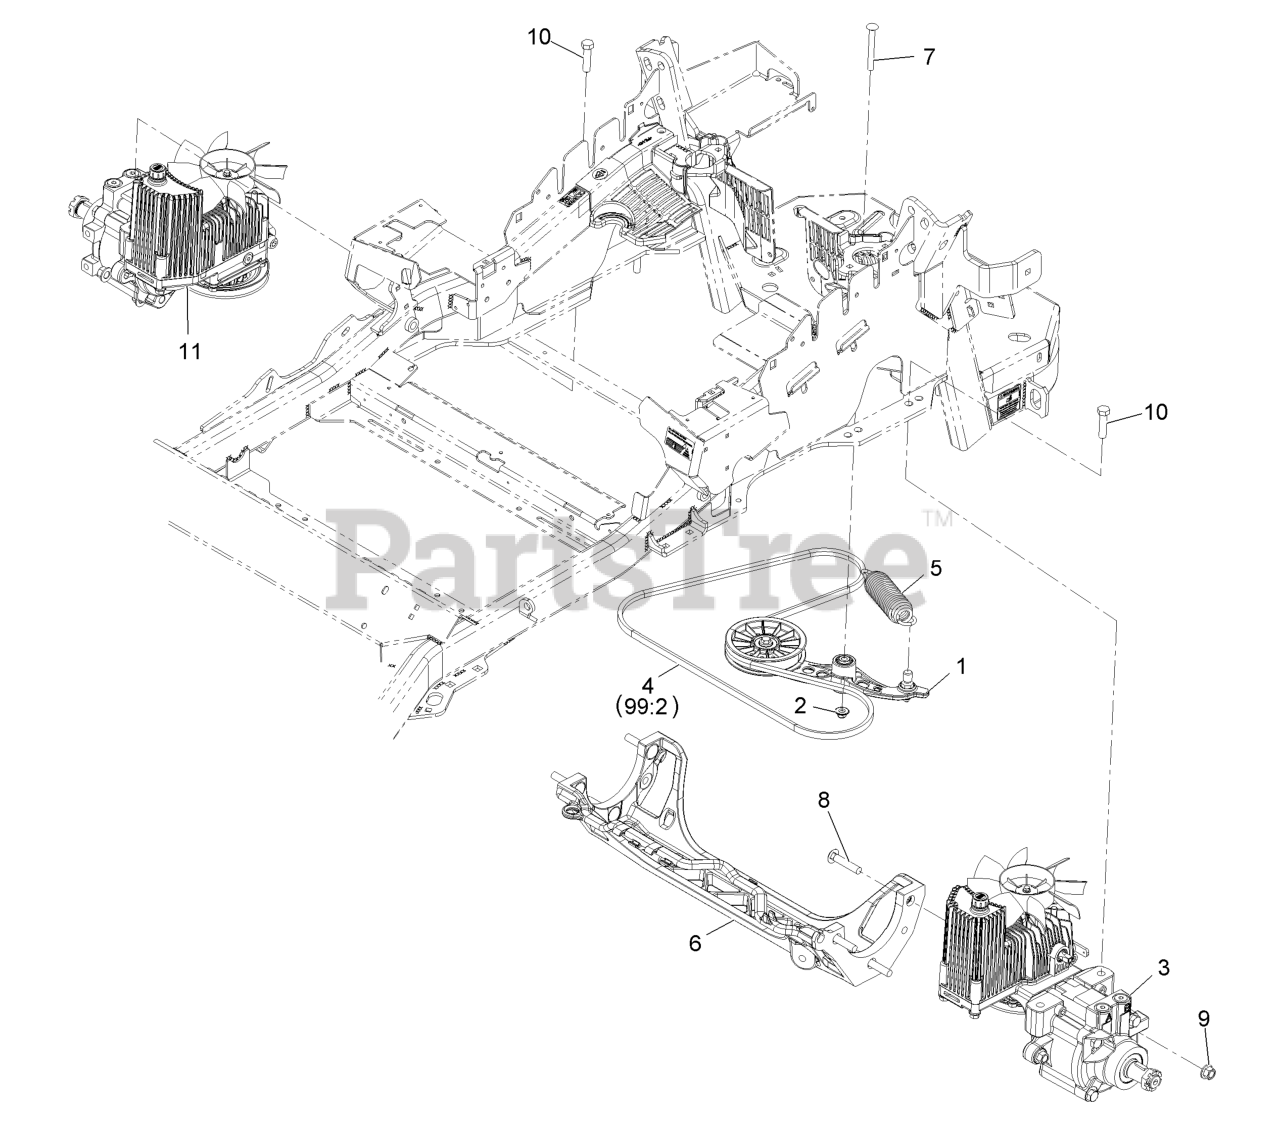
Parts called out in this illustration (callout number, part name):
1	PUMP IDLER ASM
2	Nut-Nyloc 3/8-16 Flg
4	BELT
5	SPRING-EXTENSION
7	BOLT-SHOULDER, CARRIAGE 3/8-16 X 3 1/2
8	SCREW-CARR
9	Nut-Lock 1/2-13
10	SCREW-HH
99:2	BELT
